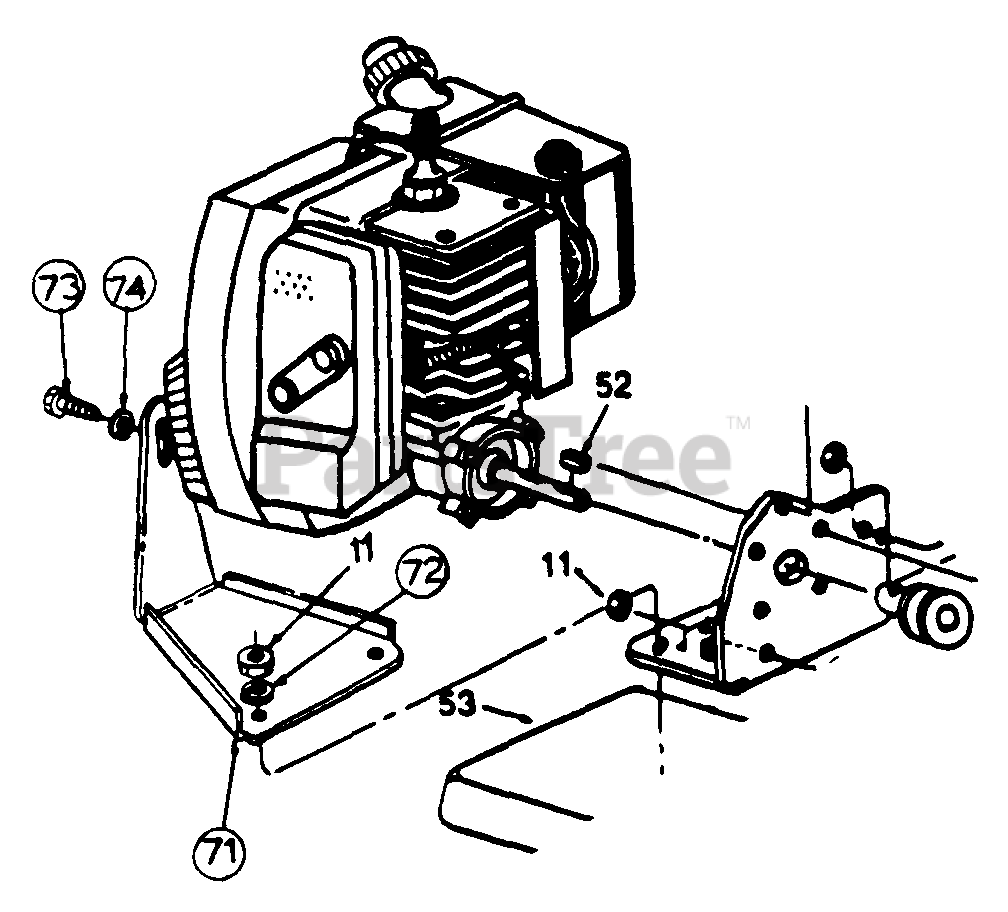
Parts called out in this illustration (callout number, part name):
11	Lock Nut 5/16-18 Thd.
52	Square Key 1/8 x 3/4"
53	Tine Shield (Red)
71	Engine Brace
72	L-Wash. 5/16" I.D.
73	Hex Wash. Hd. F-Tap Scr. #10-24 x .5" Lg.
74	L-Wash. #10 I.D.
